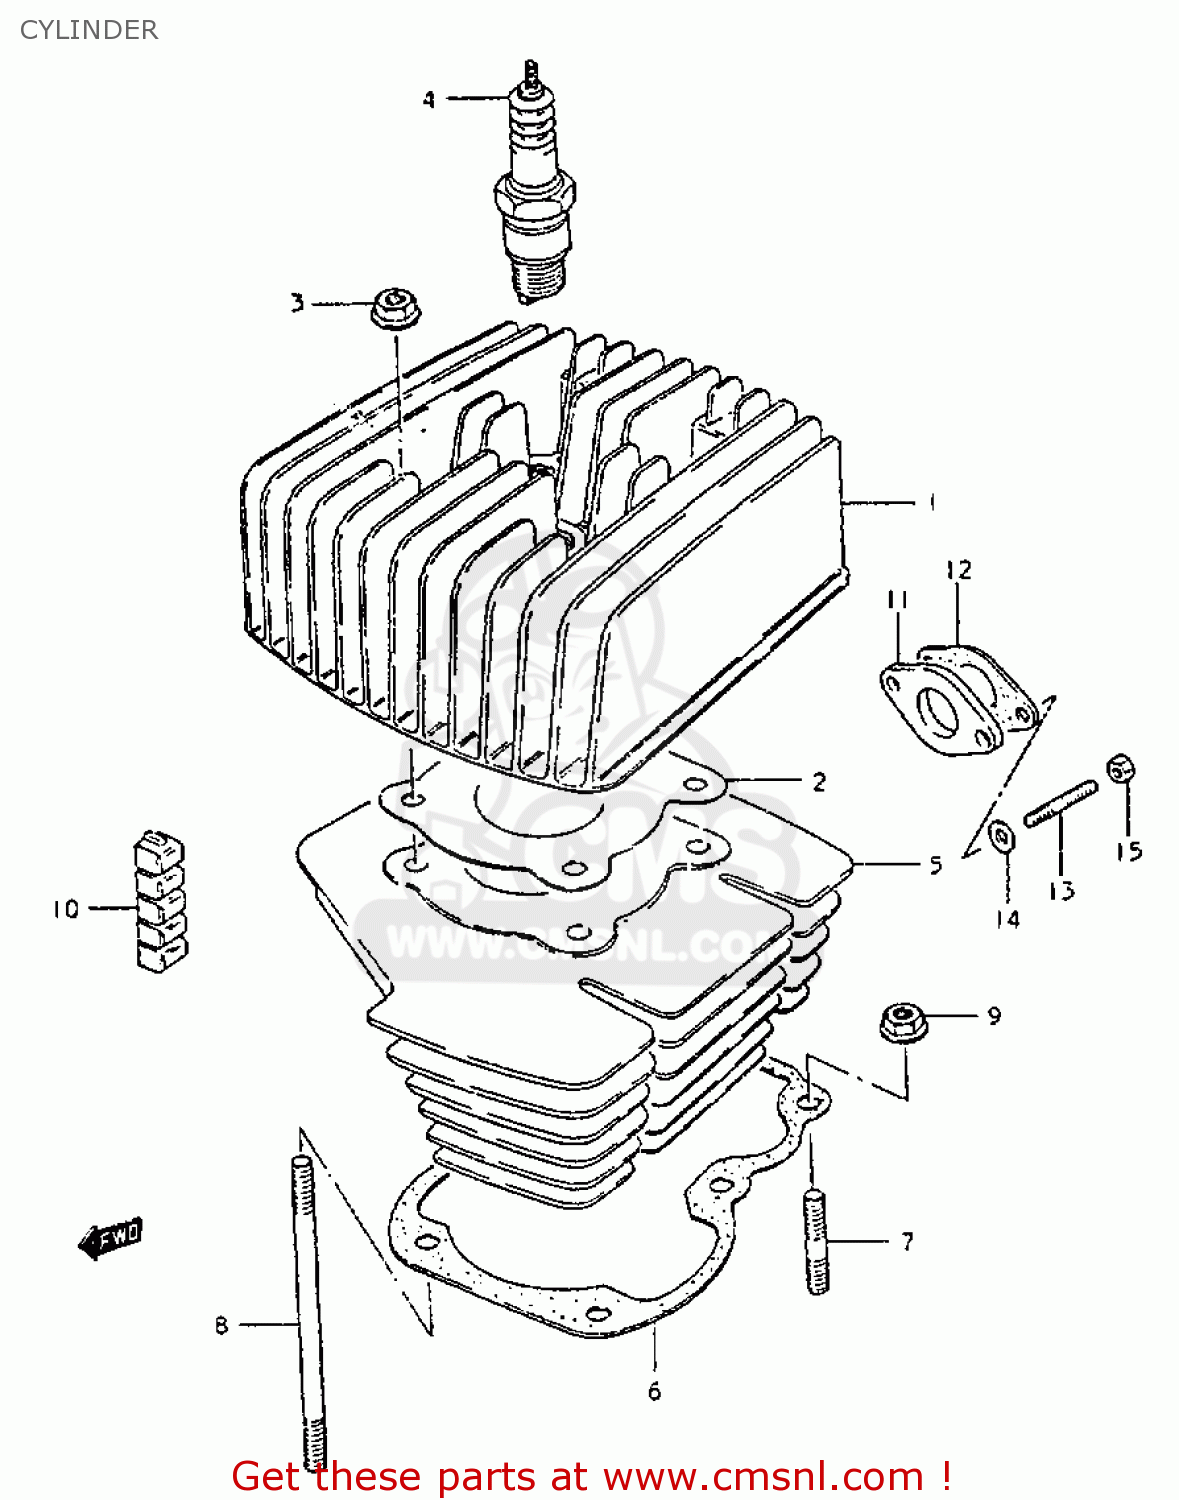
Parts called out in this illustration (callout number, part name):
1	CYLINDER HEAD
2	GASKET,CYLINDER HEAD (NAS)
3	NUT
4	SPARK PLUG (ND,W20EP)
5	CYLINDER
6	GASKET,CYLINDER (MCA)
7	BOLT,STUD
8	STUD 6X16
9	NUT
10	PAD,CYLINDER
11	INSULATOR,CARBURETOR
12	GASKET,CARBURETOR (MCA)
13	STUD BOLT
14	WASHER
15	NUT
